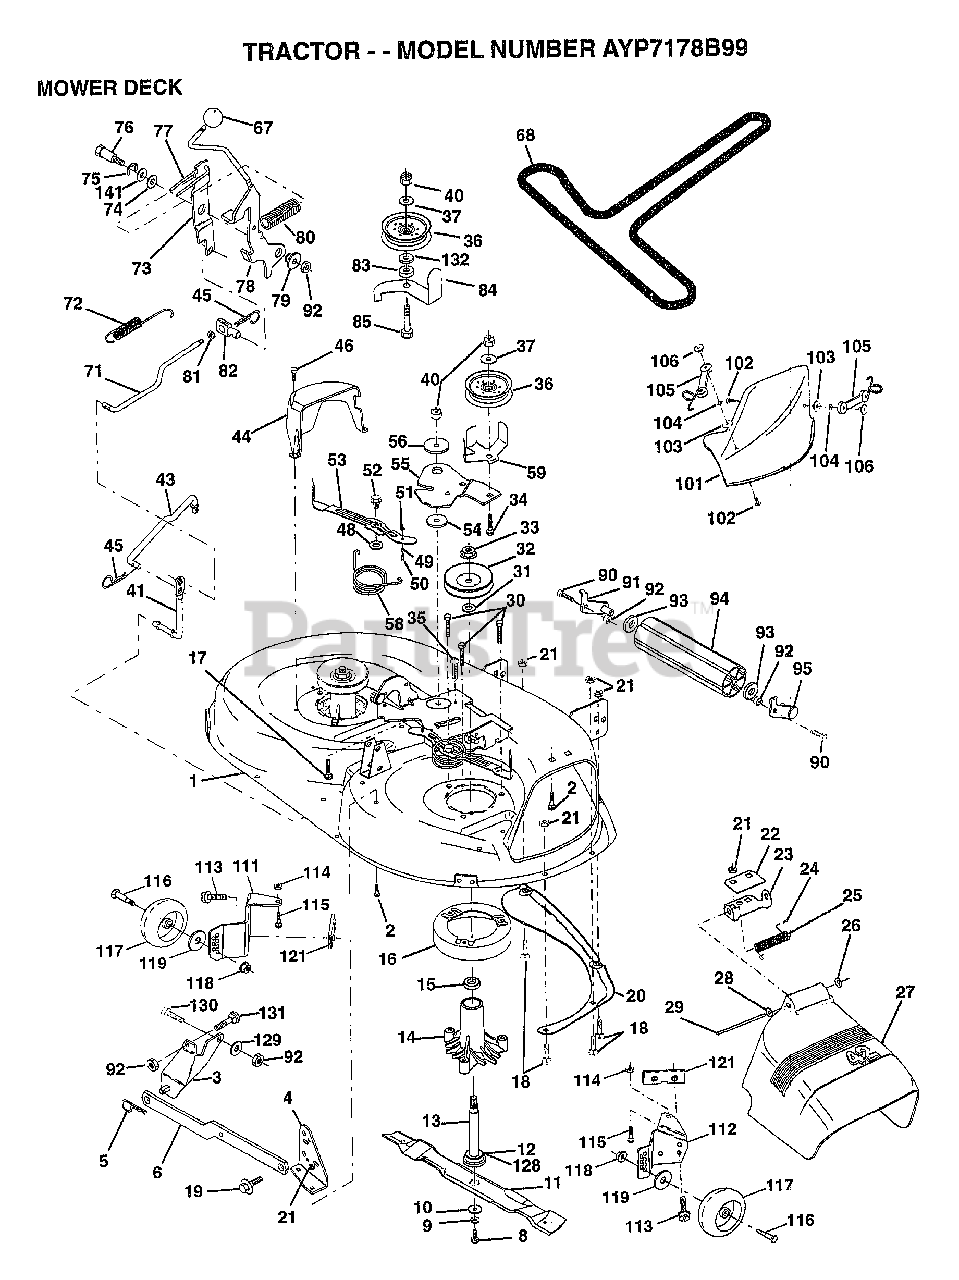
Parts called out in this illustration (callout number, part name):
1	"HOUSING ASSY.42"""
2	BOLT
3	BRKT ASM SWAY BAR
4	BRKT DECK SW BAR
8	BLADE BOLT
10	WASHER.HARD.BLADE
11	"BLADE.42"" MULCHER"
12	BEARING.BALL
14	HSG ASM MANDREL
15	BEARING
16	STRIPPER RND MWR
17	BOLT RDHD 3/8-16
18	BOLT
19	BOLT SHD 5/16-18
20	BAFFLE VORTEX 42
22	STIFFENER BRKT
23	DEFLECTOR BRKT
24	CAP-SLEEVE LT
25	SPRING TORSION
26	NUT PUSH M
27	DEFLECTOR.SHIELD
28	WASHER
29	HINGE ROD
30	"SCREW-THD ROLL,WA"
31	WASHER
32	PULLEY.MANDREL.42
34	BOLT
35	XMAS TREE FASTNER
36	FLAT IDLER PULLEY
37	WASHER
41	PIVOT ROD
43	ROD CLUTCH W/NIBS
44	GUARD MAND LH BLK
45	RETAINER M
46	SCREW.1/4-20X5/8
48	HARD SMALL WASHER
49	ROLLER ASM-CAM
50	SHOULDER BOLT
51	LOCKNUT
52	BOLT.SHLD.5/16-18
53	BRAKE PAD ARM ASM
54	HARDENED WASHER
55	ARM-IDLER
56	SPACER RETAINER
58	SPRING TORSN BRAK
59	GUARD IDLER TUV
67	KNOB.RD.7/16-14
68	BELT.V.T-PATH
71	ROD CLUTCH 38/42
72	RETURN SPRING
73	CLUTCH ARM SECOND
74	WASHER
75	RING
76	SHOULDER BOLT
77	SPRING KEEPER
78	LEVER.ASM.CLUTCH
79	BUSHING
80	SPRING.CLUTCH.MWR
81	NUT
82	TRUNION ADJ
83	WASHER
84	"KEEPER-BELT,FIXED"
85	BOLT
90	BOLT
92	NUT
93	WASHER
101	"COVER.MULCH.42"""
102	SCREW
103	WASHER #10
104	LOCKWASHER
105	LATCH ASSY.BAGGER
106	WELDNUT
111	BRACKET.GWHL.LH.
112	BRACKET.GWHL.RH.
113	SCREW
116	BOLT.SHOULDER
117	WHEEL GAGE DONUT
118	LOCKNUT
119	WASHER
121	BRACKET.EXTRD.GWL
128	WASHER.FELT.
129	WASHER
130	BOLT
132	WASHER GT
141	WASHER .T
